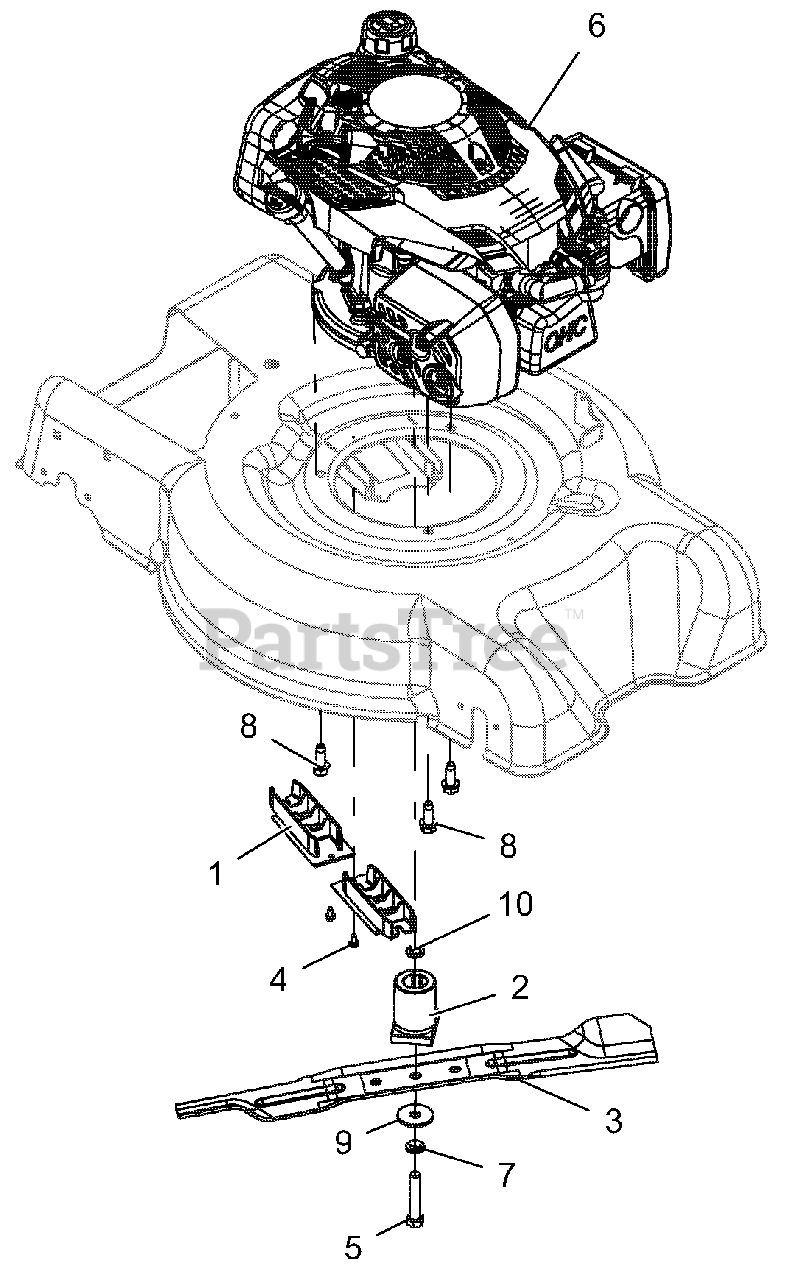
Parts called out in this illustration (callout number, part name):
1	GUIDE, BELT INNER
2	ADAPTER, BLADE
3	BLADE, MOWER 21" HIGH LIFT
4	SCR-TAP 10-24X.375 PRE-COAT 80
5	@BLT-HEX .4375-20X2.25 GR8 YWZ
6	ENGINE, SUBARU 175CC VERT
7	@WSHR-LK .44X.109 REG YWZC
8	@SCR-TAP .38-16X1.00 HWH TR YZ
9	WSHR-FL-STL .4375X1.50X.125 YZ
10	WSHR-FL-STL .459X.750X.105 YZC
